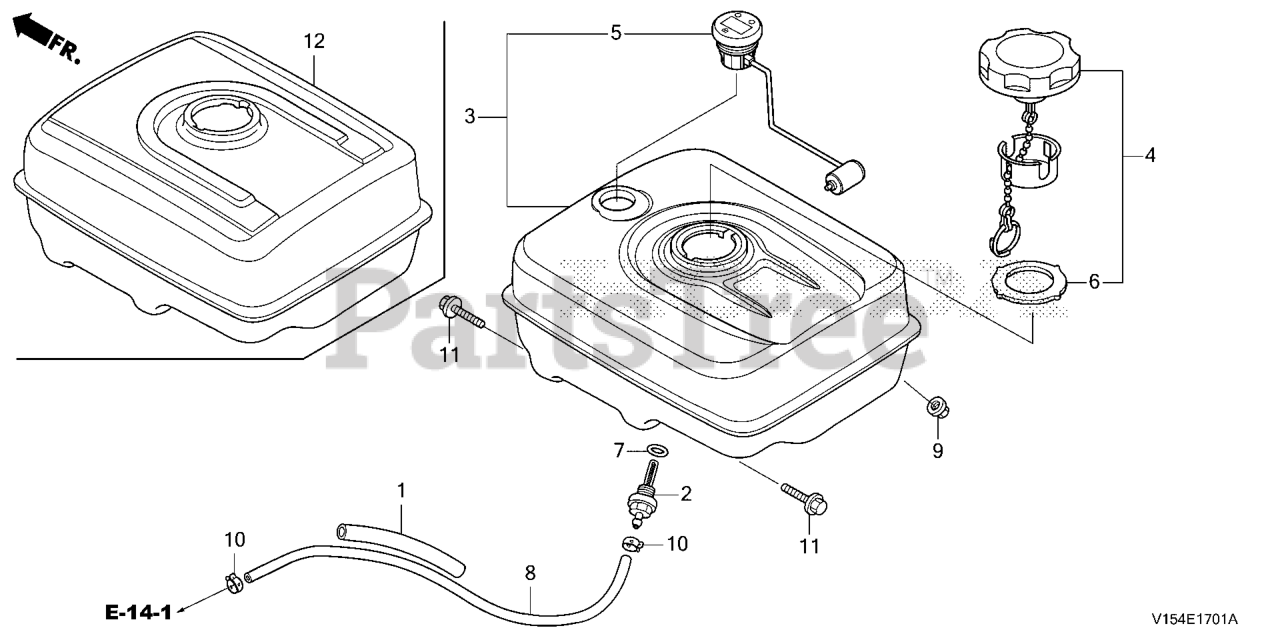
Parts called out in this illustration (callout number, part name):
1	RUBBER, SUPPORTER (107MM)
2	JOINT, FUEL TANK
4	CAP, FUEL FILLER
6	GASKET, FUEL FILLER CAP
6	GASKET, FUEL FILLER CAP (39X62X3) (TOUYOUSYA)
7	O-RING (14MM) (ARAI) Use up to Engine SN 2949254.
8	TUBE, FUEL (4.5X235)
9	NUT, FLANGE (8MM)
10	CLIP, TUBE (D8)
11	BOLT, FLANGE (8X28)
12	TANK, FUEL *R280*
